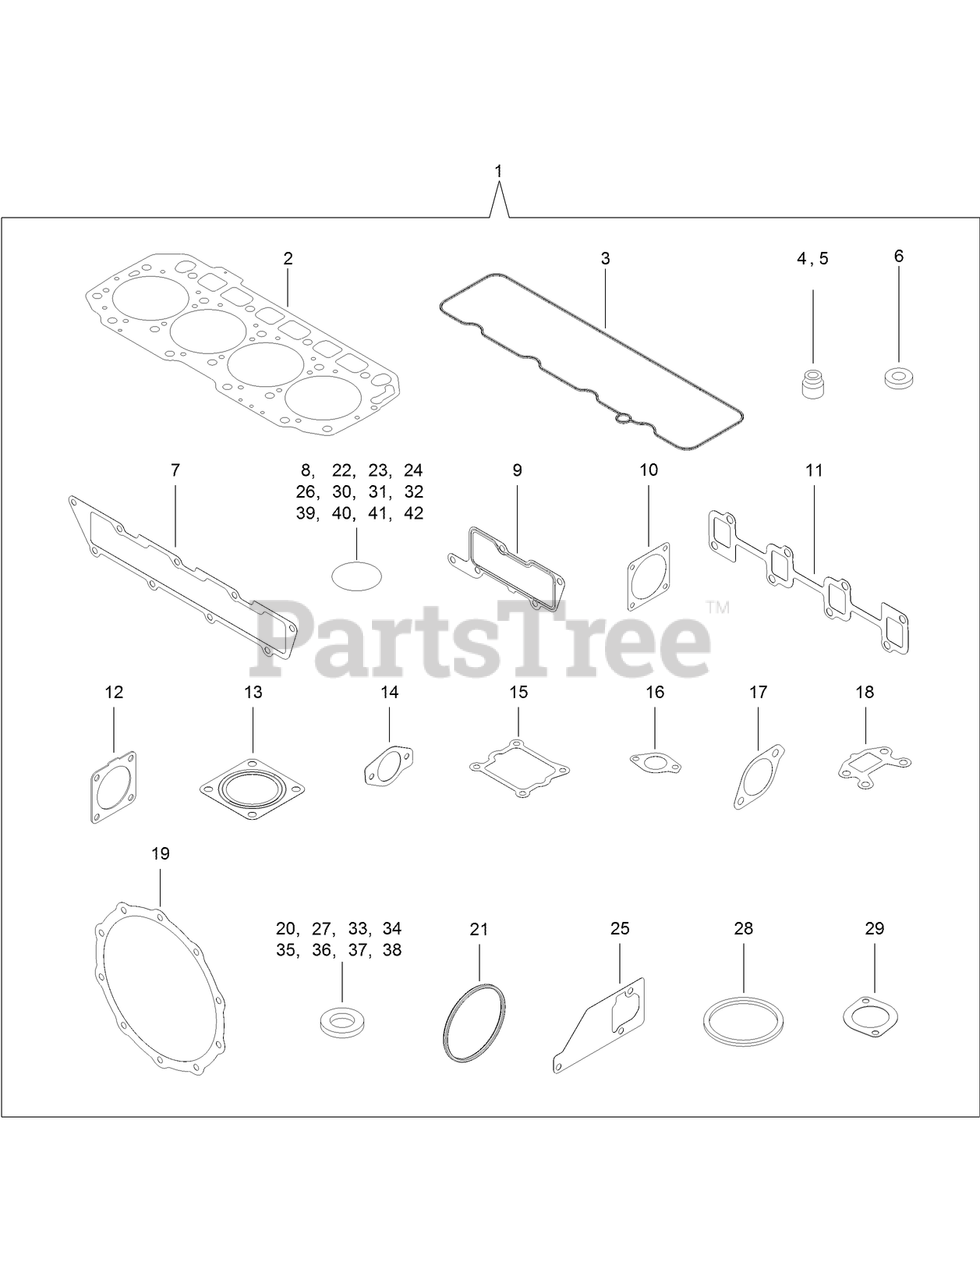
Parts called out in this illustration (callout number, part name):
1	GASKET SET
2	GASKET-HEAD, CYLINDER
3	GASKET-COVER, HEAD
4	SEAL-STEM, VALVE
5	SEAL-STEM, VALVE
6	GASKET-INJECTOR
7	GASKET-MANIFOLD
8	O-RING
9	GASKET-COLLECTOR
10	GASKET-THROTTLE
11	GASKET-MANIFOLD
12	GASKET
13	GASKET-SILENCER
14	GASKET-COOLER, E G R
15	GASKET-V SPACER, E G R
16	GASKET
17	GASKET-IN, E G R-V
18	GASKET-OUT, E G R-V
19	GASKET-D P F
20	GASKET-SENSOR
21	PACKING-WASHER
22	O-RING
23	O-RING
24	O-RING
25	GASKET-PUMP, WATER
26	O-RING
27	GASKET
28	GASKET-THERMOSTAT
29	GASKET-COVER, THERMOSTAT
30	O-RING
31	O-RING
32	O-RING
33	WASHER-SEAL
34	WASHER-SEAL
35	WASHER-SEAL
36	WASHER-SEAL
37	GASKET
38	GASKET
39	O-RING
40	O-RING
41	O-RING
42	O-RING
